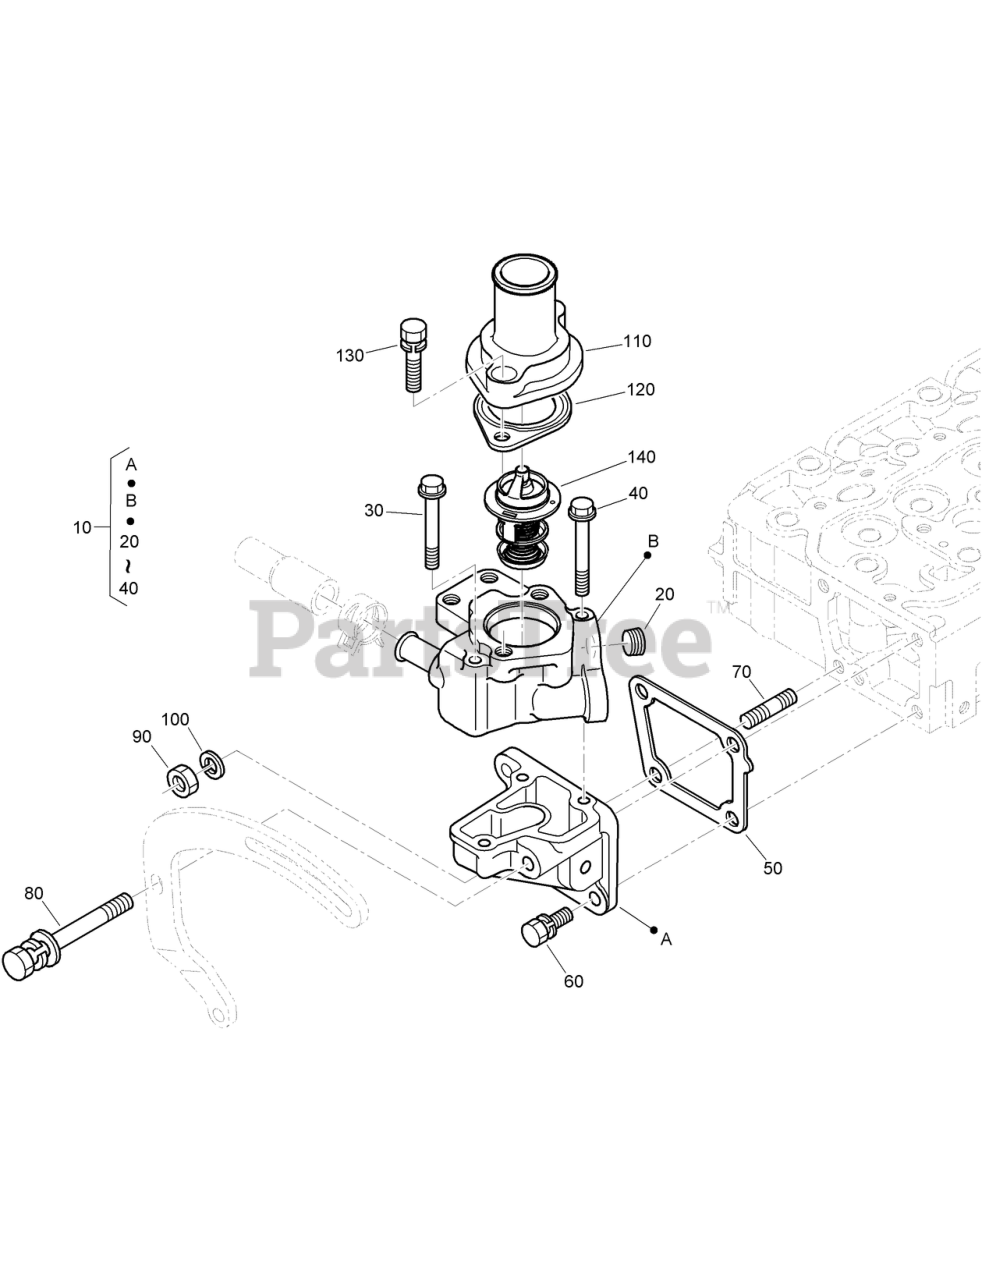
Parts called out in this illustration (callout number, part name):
10	WATER FLANGE ASM
30	BOLT-FLANGE
40	Bolt-Flange
50	GASKET-FLANGE, WATER
100	WASHER-SPRING, LOCK
110	COVER-THERMOSTAT
120	GASKET-THERMOSTAT
140	THERMOSTAT ASM
